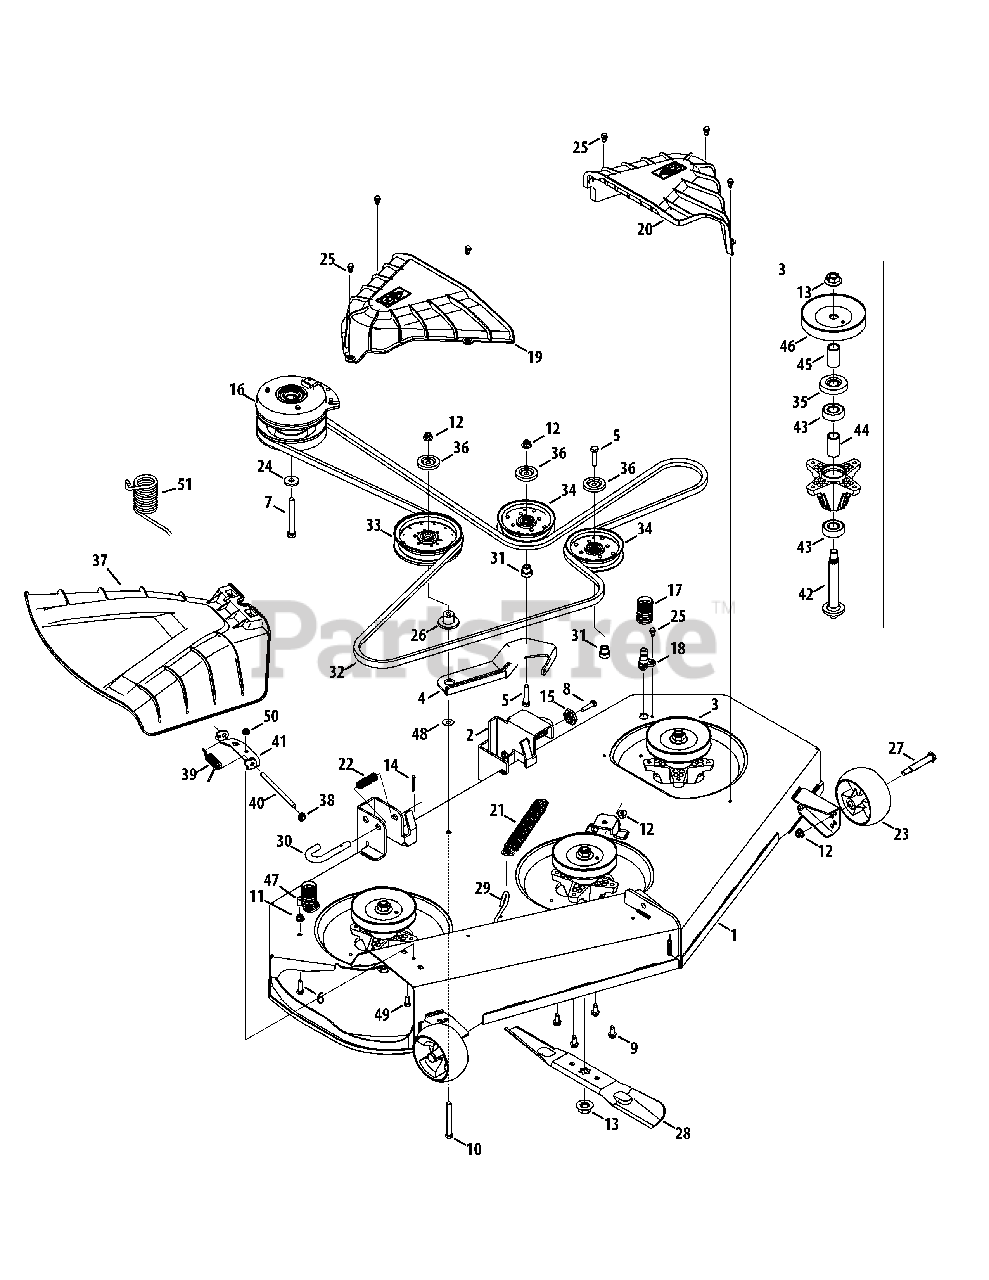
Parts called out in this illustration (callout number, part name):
1	54" Deck
2	Deck Lift Bracket
3	Spindle Assembly
4	Idler Arm Assembly
5	Hex Cap Screw, 3/8-16 x 1.75
6	Hex Cap Screw, 5/16-18 x 1.00
7	Hex Cap Screw, 7/16-20 x 3.50
8	Hex Cap Screw, 3/8-16 x 1.50
9	Hex Washer Screw, 5/16-18 x .750
10	Hex Cap Screw, 3/8-16 x 3.25
11	Flange Lock Nut, 5/16-18
12	Flange Lock Nut, 3/8-16
13	Hex Flange Nut, 5/16-18
14	Cotter Pin, 5.32 x 1.25
15	Deck Adjustment Gear
16	Electric PTO Clutch
17	Water Nozzle Adapter
18	Deck Wash Nozzle
19	Belt Cover, RH
20	Belt Cover, LH
21	Extension Spring, 1.25 OD x 1.751
22	Compression Spring, .66 x 1.9
23	Deck Ball Wheel, 5.0
24	Flat Washer, .450 x 1.25 x .164
25	Shoulder Screw, 1/4-20 x 0.50
26	Shoulder Spacer
27	Shoulder Screw, .5 x 2.5 x 3/8-16
28	Blade, 18.67
29	Deck Spring Rod
30	Deck Hanger Rod
31	Shoulder Spacer
33	Idler Pulley, 5.00 Dia.
34	Idler Pulley, 4.25 Dia
35	Bearing Shield
36	Pulley Cap
37	Chute Assembly
38	Push Cap
39	Spring, Torsion, .440 ID x 1.75
42	Spindle Shaft, 6.11 Long
43	Ball Bearing
44	Spacer, .792 x 1.060 x 1.860
45	Spacer, .792 x 1.060 x 1.782
46	Deck Pulley
47	Cap, .290 x .500
48	Flat Washer, .385 x 1.00 x .030
49	Hex Cap Screw, 1/4-20 x .62
50	Nut, Flange Lock, 1/4-20, Nylon
51	Torsion Spring, 1.323 ID x 2.83 LG
